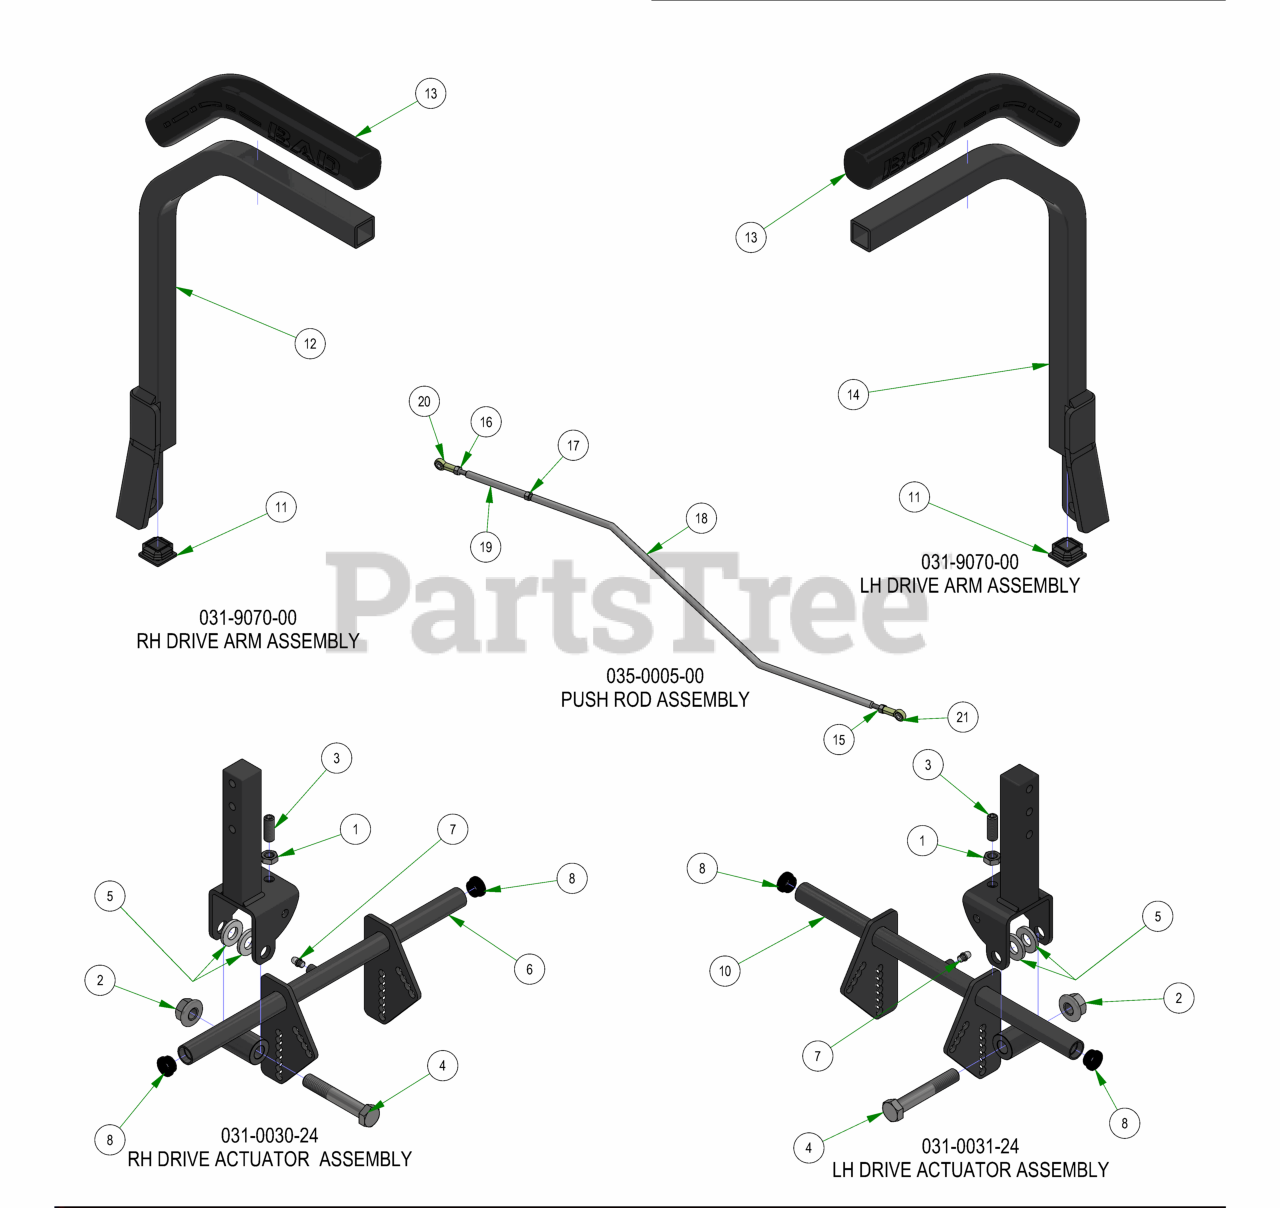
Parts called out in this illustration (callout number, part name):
1	3/8-16 Half Jam Nut
2	1/2-13 NYLON INSERT FLANGE LOCKNUT ZINC
3	3/8-16 X 1 SOCKET SET SCREW (CUP POINT) PLAIN
4	1/2-13 X 3 HEX CAP SCREW (GR.5) ZINC
5	.505 ID X 1.000 OD X .125 THICK FLAT WASHER NYLON
6	2019 Drive Arm Actuator right - Weldment
7	1/4" Press in Grease Fitting
8	2019 Drive Arm Bushing
9	R Series Square Drive Arm Pivot
10	2019 Drive Arm Actuator left - Weldment
11	9565K52_Polyethylene Square Plug
12	R Series Square Drive Arm RH Weldment
13	R-Series Square Drive Grip
14	R Series Square Drive Arm LH Weldment
15	5/16" RH Fine Threaded Jam Nut
16	5/16" LH Fine Threaded Jam Nut
17	3/8" Fine Threaded Jam Nut
18	2019 Renegade Push Rod
19	2019 Renegade Push Rod Adjuster
20	Spherical Rod End - Outlaw
21	Spherical Rod End - Outlaw
